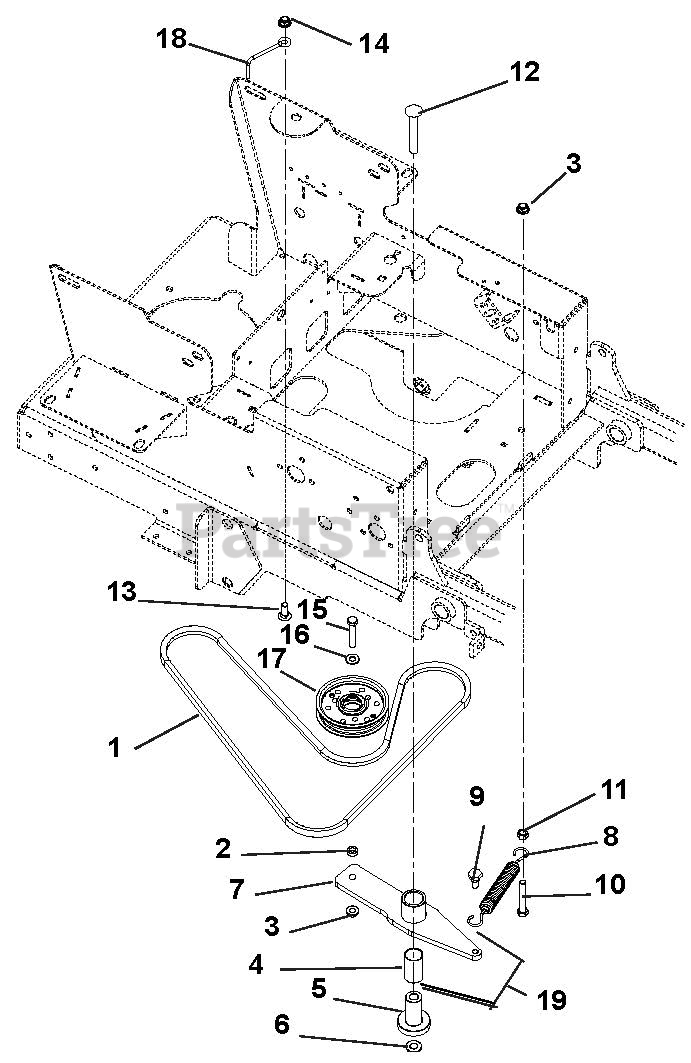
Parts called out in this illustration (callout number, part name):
1	Belt, 4L 67.47 Wrapped
2	Bushing, Sleeve .377 x .624 x .235
3	Nut, .38-16 Nyloc Flange
4	Bushing, 1.00 x 1.125 x 1.936
5	Bearing, Pedestal
6	Nut .50-13 Nyloc Flange
7	Weldment, Hydro Drive Idler Arm
8	Spring, Extension
9	Bolt, Shoulder EP .38-16 x .30 Hex
10	Bolt, Hex .38-16 x 2.50 Grade 5
11	Nut, Locking-Center .375-16
12	Bolt, Round Head Square Neck .50-13 x 3.50
13	Bolt, Round Head Square Neck .38-16 x 1.00 Grade 5
14	Nut, .38-16 Nyloc Flange
15	Bolt, Hex .38-16 x 2.00 Grade 5
16	Washer, Flat-Steel .406 x .812 x .065
17	Assembly, 4" Idler
18	Belt Finger
19	Assembly, Ground Drive Idler
